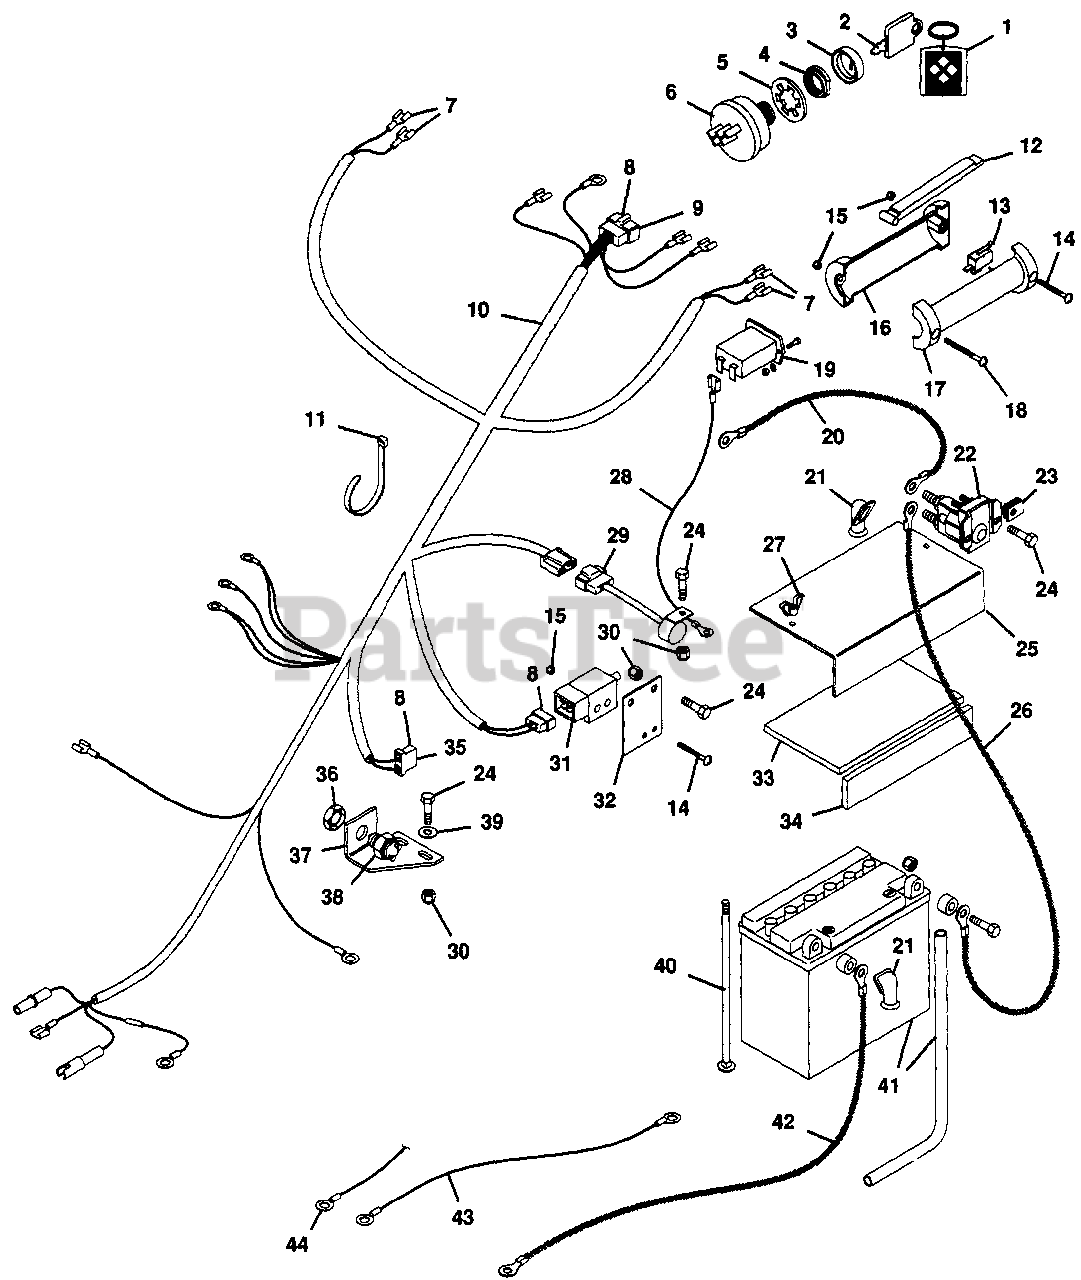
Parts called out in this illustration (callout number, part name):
1	Chain, Key
2	Key, Ignition Switch
3	Boot, for 9/16 Switch
4	Nut, 9/16-24 for Switch
5	Washer, Lock
6	Switch, Ignition
7	Terminal, Female
8	Terminal
9	Connector
10	Harness, Wiring
11	Tie Wrap, Black
12	Lever
13	Switch
14	Screw, Machine 10-24x.625 PHD
15	Nut, Lock 10-24
16	Handle, R.H.
17	Handle, L.H.
18	Screw, Mach. 10-24x1.50 PHDCR
19	Hourmeter
20	Cable, Solenoid to Starter
21	Boot, Battery Cable
22	Switch, Magnetic
23	Nut, Speed 1/4-20
24	Bolt, Hex 1/4-20x.750
25	Cover, Battery
26	Cable, Battery to Solenoid
27	Nut, Wing 1/4-20
28	Wire, Instrument Panel
29	Module, Interlock
30	Nut, Lock 1/4-20
31	Switch, Interlock
32	Bracket, Interlock Switch
33	Pad, Battery
34	Pad, Battery
35	Connector, 2-Wire Switch
36	Nut, Stamped 9/16-18
37	Bracket, Interlock Switch
38	Switch, Neutral Start
39	Washer, Flat .281x.625x.065
40	Bolt, 1/4-20x7.00 Rd Hd Sq Nk
41	Battery, 12 Volt
42	Cable, Negative Battery
43	Wire, Ground
44	Terminal, Ring Tongue
